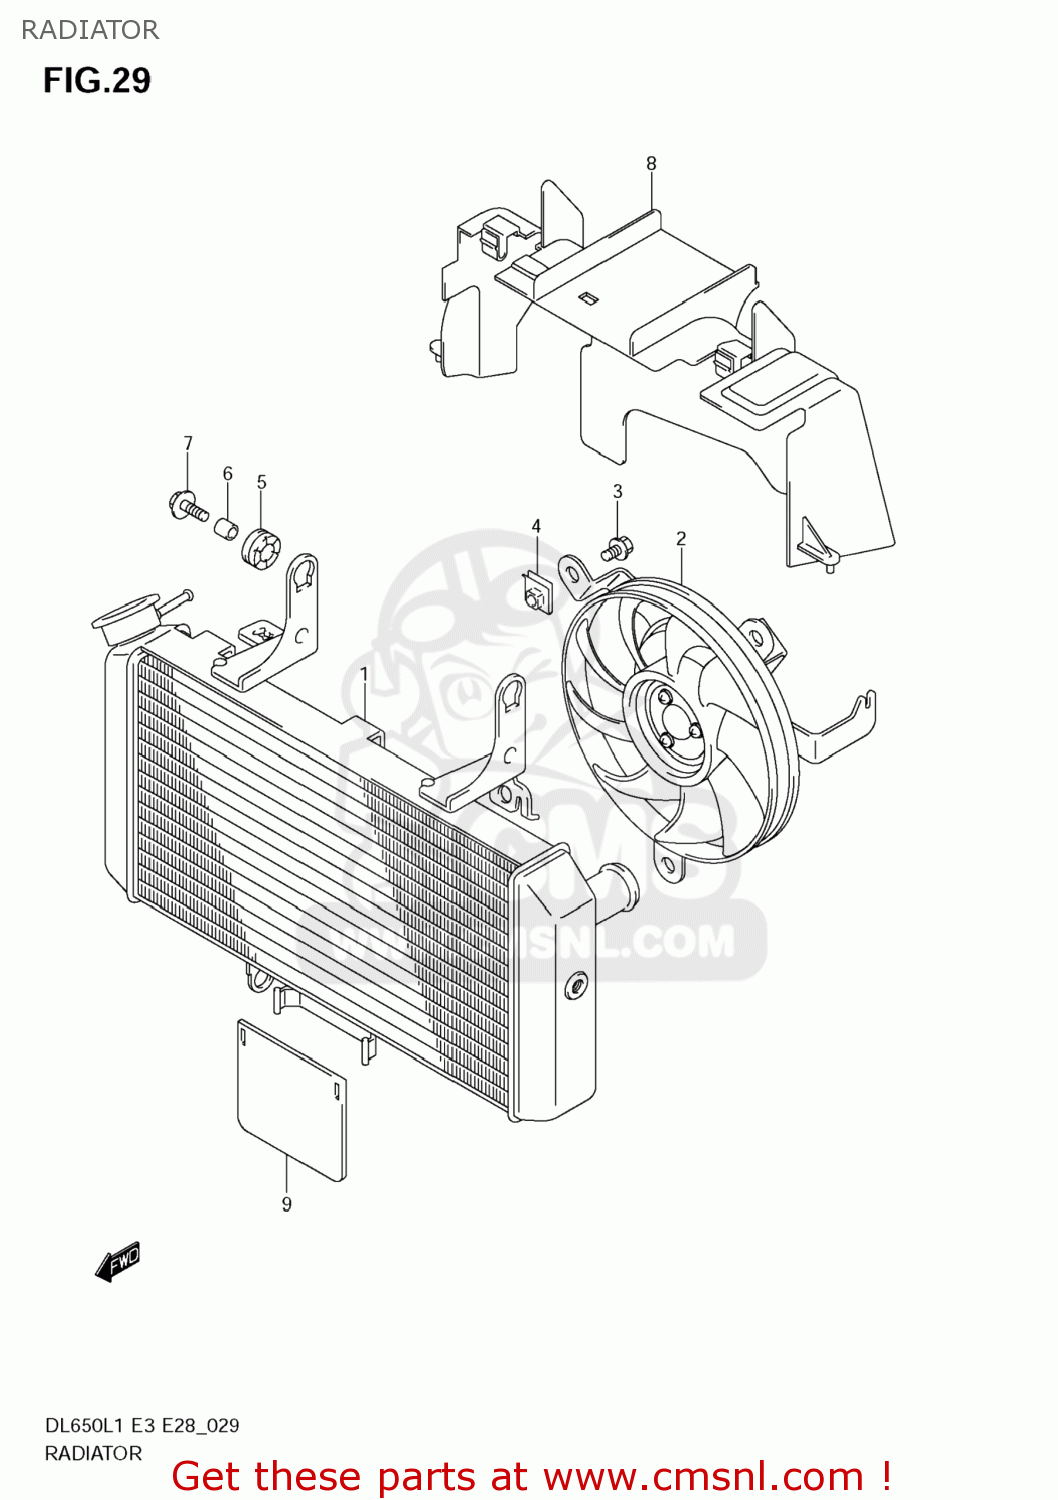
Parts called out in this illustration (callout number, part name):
1	RADIATOR ASSY,WATER
2	FAN ASSY,RADIATOR
3	BOLT,FAN ASSY
4	NUT,FAN ASSY
5	CUSHION
6	SPACER(6.5X10X12)
7	BOLT(6X25)
8	SHIELD,RADIATOR HEAT
9	RUBBER,RADIATOR UNDER
